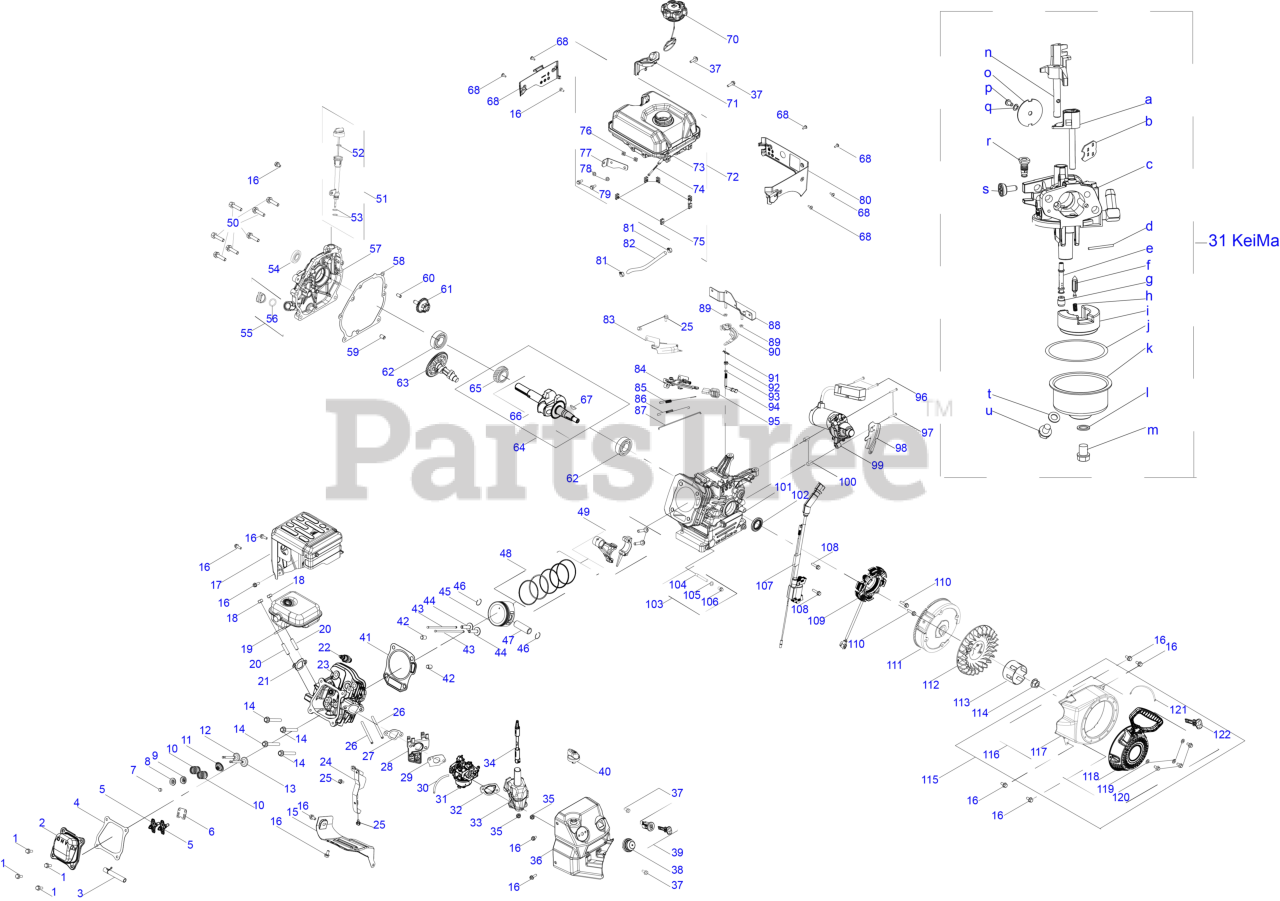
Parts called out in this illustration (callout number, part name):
1	BOLT M6 x 16
2	VALVE COVER
3	BREATHER HOSE
4	VALVE COVER GASKET
5	ROCKER ARM KIT
6	ROCKER ARM BASE
7	EXHAUST VALVE ADJUSTER
8	EXHAUST VALVE SPRING RETAINER
9	INTAKE VALVE SPRING RETAINER
10	VALVE SPRING
11	INTAKE VALVE SEAL
12	EXHAUST VALVE
13	INTAKE VALVE
14	BOLT M8-1.25 x 55 GR10.9
15	AIR SHIELD
16	BOLT M6-1 x 12 GR8.8
17	MUFFLER GUARD
20	STUD M8 x 36
21	MUFFLER GASKET
22	SPARK PLUG (F6RTC/RN11YC/BPR6ES)
23	CYLINDER HEAD
24	SNOW GUARD
25	BOLT M6-1 x 12 GR8.8
26	STUD M6 x 90
27	CARBURETOR INSULATOR GASKET
29	CARBURETOR GASKET
30	PRIMER HOSE
31	Carburetor
32	CARBURETOR GASKET PLATE
33	AIR/HEATER INTAKE BOX
34	CHOKE LEVER
36	CONTROL PANEL
37	BOLT M6-1 x 18 GR8.8
39	ENGINE KEY SWITCH ASSEMBLY
41	CYLINDER HEAD GASKET
42	PIN (10MMx16MM)
46	PISTON PIN SNAP RING
48	PISTON RING SET
49	CONNECTING ROD
51	DIPSTICK ASSEMBLY
53	OIL FILL TUBE O-RING
56	O-RING 15.8 x 2.5
57	CRANKCASE COVER
58	CRANKCASE GASKET
59	DOWEL PIN 9 X 14
60	DOWEL PIN 7 X 14
61	GOVERNOR GEAR
64	Not Serviceable/ Components Only
65	DRIVE TIMING GEAR
67	WOODRUFF KEY
68	BOLT: M5 x 14
69	FUEL TANK SHROUD (REAR)
73	Not Serviceable/ Order Complete Assembly
74	FUEL FILTER
75	FUEL TANK MOUNT
77	FUEL TANK MOUNT TAB
78	WASHER 6.5 x 1.5 x 12
79	BOLT M6 x 20
80	FUEL TANK SHROUD (LH)
81	CARBURETOR HOSE CLAMP
83	GOVERNOR SHIELD
84	GOVERNOR GEAR BRACKET ASSEMBLY
85	GOVERNOR SPRING
86	THROTTLE SPRING
87	THROTTLE LINKAGE
88	FUEL TANK BRACKET
90	GOVERNOR LEVER
92	OIL SEAL 6x11x4
95	THROTTLE LEVER KNOB
96	SCREW M4x48
97	BOLT M6-1 x 32 GR8.8
98	LOWER HOUSING
99	ELECTRIC STARTER
103	OIL DRAIN PIPE
104	OIL DRAIN PIPE
105	FLAT WASHER
106	OIL DRAIN PLUG
107	IGNITION MODULE
108	BOLT M6-1 x 25 GR8.8
109	CHARGING COIL
110	BOLT-M6-1 x 28 GR8.8
112	COOLING FAN
113	STARTER CUP
114	FLYWHEEL NUT M14-1.5
115	Not Serviceable/ Components Only
116	RECOIL STARTER
117	BLOWER HOUSING
118	RECOIL STARTER
119	FLAT WASHER
120	BOLT M6 x 10
121	CABLE TIE 3x150
122	IGNITION KEY
